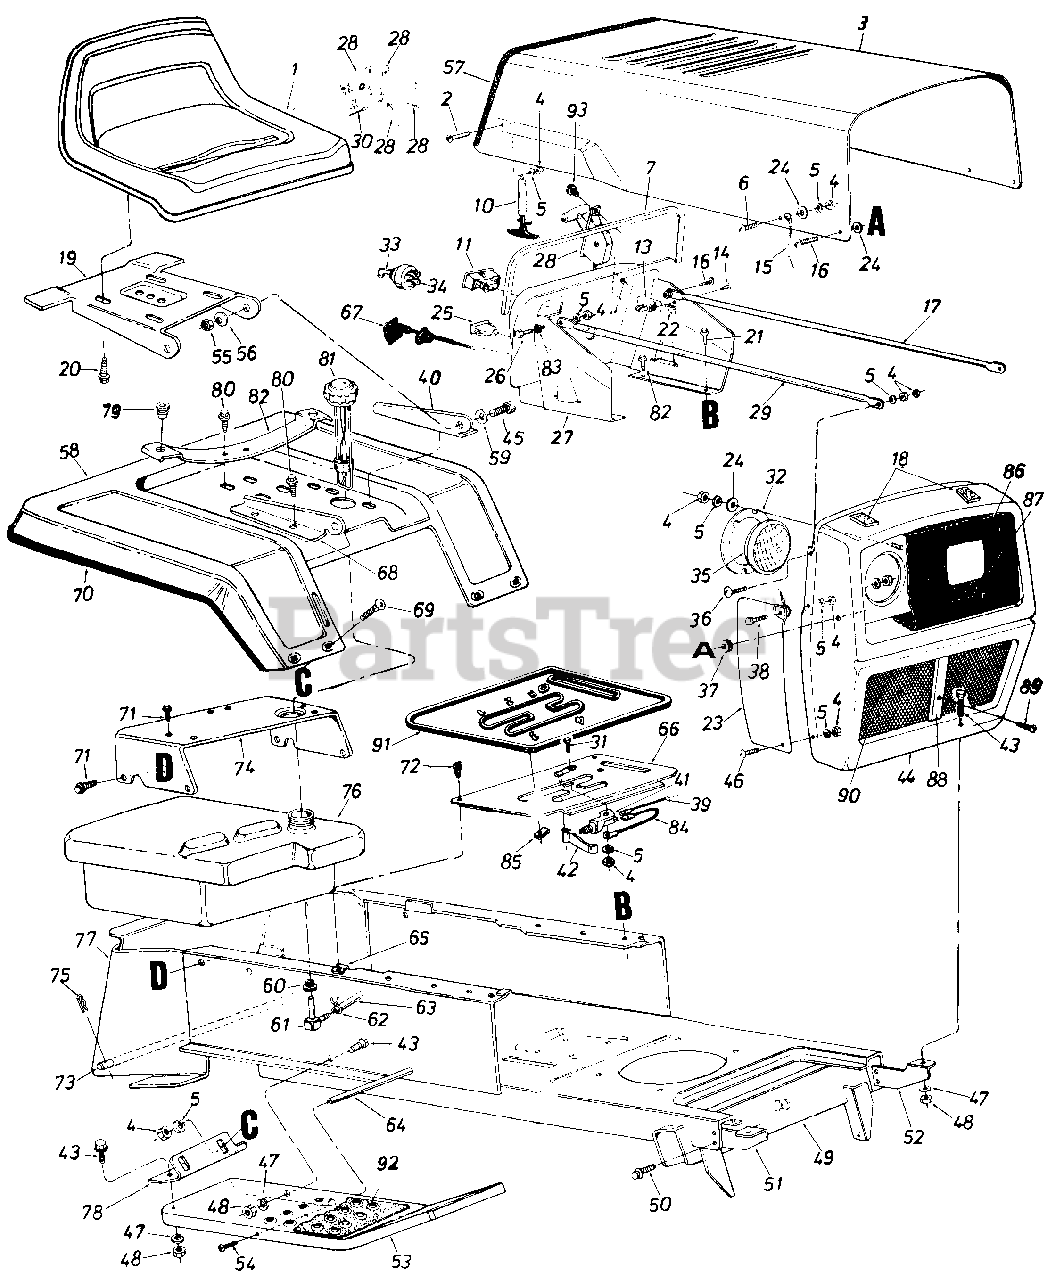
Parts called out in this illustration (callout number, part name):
1	Seat Assembly
2	Truss Mach. Scr. 1/4-20 x .50" Lg.*
5	L-Wash. 1/4" Scr.
6	Truss Mach. Scr. 1/4-20 x .50" Lg.
7	Vinyl Molding Strip-29"
10	Hood Latch Ass'y.
11	Ammeter
13	Circuit Breaker 8 Amp.
14	Hex Tap Scr. #10 x .50" Lg.
15	Hood Stop
16	Truss Mach. Scr. 1/4-20 x .75" Lg.*
17	Grille Positioning Rod
18	PVC Foam Strip '/2 x 1.00" x 2.00" Lg.
19	Seat Pivot Brkt.
20	Hex Wash. Hd. AB-Tap Scr. 3/8 x .75" Lg.
21	Hex Thd. Rolling Scr. 1/4" x .50" Lg.
22	Speed Nut #10Z
23	Grille Side Panel-R.H.
24	Fl-Wash. 1/4" I.D.
25	Light Switch
26	Truss Hd. Scr. 1/4-20 x 1.00" Lg.
27	Dash Panel Ass'y.
28	Throttle Control Box Comp.
29	Grille Positioning Rod
30	Trottle Control Cable
31	Hex Bolt 1/4-20 x .50" Lg.
32	Head Lamp Retainer
33	Ignition Key
34	Ignition Switch
35	Head Lamp
36	Truss Machine Scr. 1/4-20 x .75" Lg.
37	Rubber Wash. .50" I.D. x 1.00 O.D. x .25 Thk.
38	Truss Mach. Scr. 1/4-20 x .50" Lg.
39	Reverse Lockout Wire Harness
40	Seat Bracket-L.H.
41	Safety Switch
42	Switch Actuator Spring Lever
43	Hex Scr. 5/16-18 x .75" Lg.
44	Grille Ass'y.
45	Hex Bolt 5/16-18 x .75" Lg.
46	Truss Mach. Scr. 1/4-20 x .50" Lg.
47	L-Wash. 5/16" Scr.
48	Hex Nut 5/16-18 Thd.
49	Lower Frame Ass'y.
50	Hex Thd. Rolling Scr. 5/16" x.75" Lg.
51	Grille Mount Brkt.-R.H.
52	Grille Mount Brkt.-L.H.
53	Running Board-R.H.
54	Truss Mach. Scr. 5/16-18 x .75" Lg.
55	Hex Cent. L-Nut 5/16-18 Thd.
56	Bell-Wash. .34" I.D. x .88 O.D.
57	Vinyl Moulding Strip-30"
58	Fender Ass'y.-R.H.
59	Bell-Wash. .34" I.D. x .88" O.D.
60	Bushing
61	90ø Nipple
62	Hose Clamp 3/8"
63	Gas Line 46" Lg.
64	Running Board Rod
65	Speed Nut #10-24
66	Transmission Cover Ass'y.
67	Choke Control Comp.
68	Seat Bracket-R.H.
69	Carr. Bolt 1/4-20 x .50" Lg.
70	Trim Strip-81" Lg.
71	Hex Thd. Rolling Scr. 5/16-24 x .75" Lg.
72	Truss Hd. Scr. #10 x .50" Lg.
73	Hitch Rod
74	Seat Mounting Channel
75	Internal Cotter Pin
76	Gas Tank
77	Hitch Plate
80	Hex Wash. Hd. Self-Tap Scr. 5/16-18 x .50" Lg.
81	Gas Gauge
82	Seat Spring
83	External Wash. 1/4" I.D.
84	Electric Wire
85	Speed Nut 1/4" Stud
86	Headlight Bezel
87	Hex Wash. Hd. F-Tap Scr. #8-32 x .38" Lg.
88	Center Moulding
89	Truss Mach. Scr. #10-24 x .62" Lg.
90	Grille Screen
91	Transmission Cover
92	Foot Pad
93	Truss Mach. AB-Tap Scr. #10 x .50" Lg.
